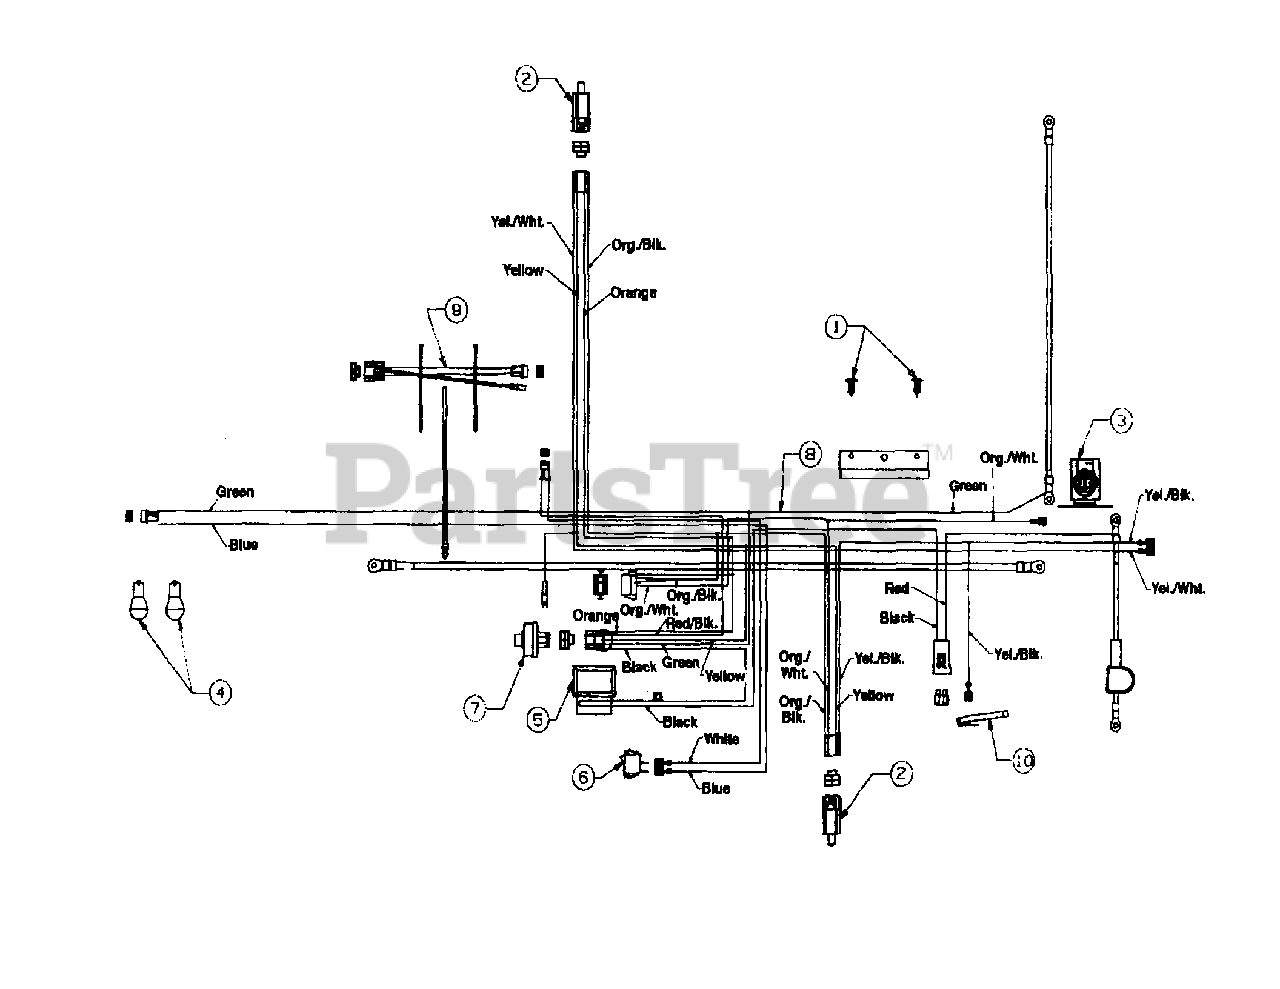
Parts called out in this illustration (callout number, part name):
2	Safety Switch
3	Solenoid
4	Bulb (Headlight)
5	Ammeter
6	Light Switch
7	Ignition Switch
8	Wire Harness
9	Wire Harness Adapter
10	Wire Harness (Monitor)
